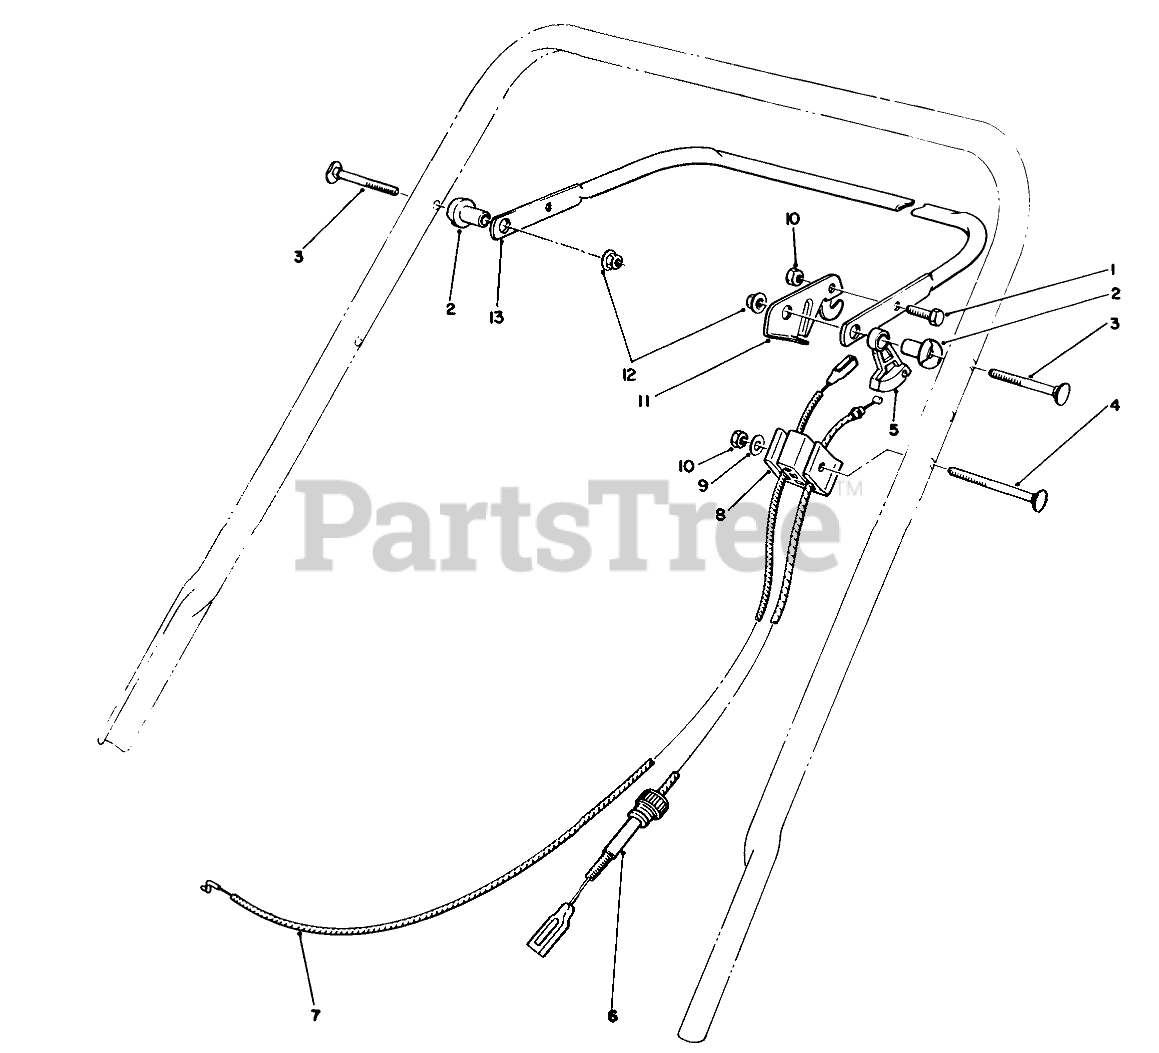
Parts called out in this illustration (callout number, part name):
1	SCREW-HH
2	SPACER-SUPPORT
3	5/16-18 X 2 HNDLE SCREW
4	HANDLE SCREW
5	LEVER-TRACTION
6	CABLE-TRACTION
7	BRAKE CONTROL
8	SUPPORT-CABLE
9	WASHER-FLAT
10	NUT-LOCK, NI
11	LEVER-CONTROL
12	NUT-LOCK, NI
13	Bar-Control
